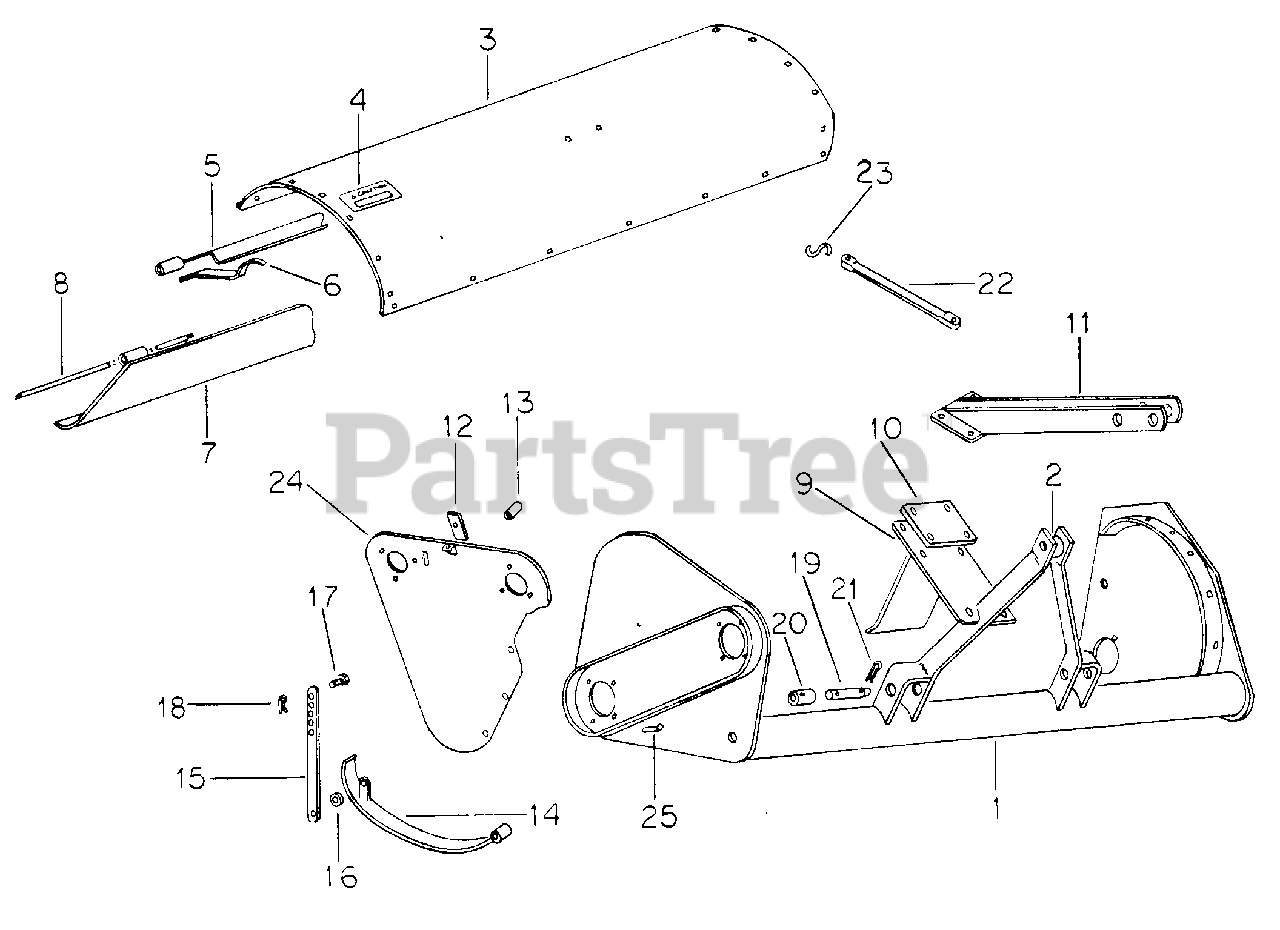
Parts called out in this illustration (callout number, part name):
2	Spacer, 1/2 X 1.125 X/Strg Pipe
3	Shroud w/Product Graphic
4	Product Graphic, Caution
5	Bracket, Hinge
7	Blade, Level
8	Rod, Hinge
9	Support, Mount
12	Bar, Idler Support -Strap
13	Spacer, 1/2 X 2 Frame Support
15	Bar, Adjust
17	Bolt, Special
20	Spacer, Pin
22	Strap, Tie
24	Cover, Inner
25	Bolt, Special Carriage
